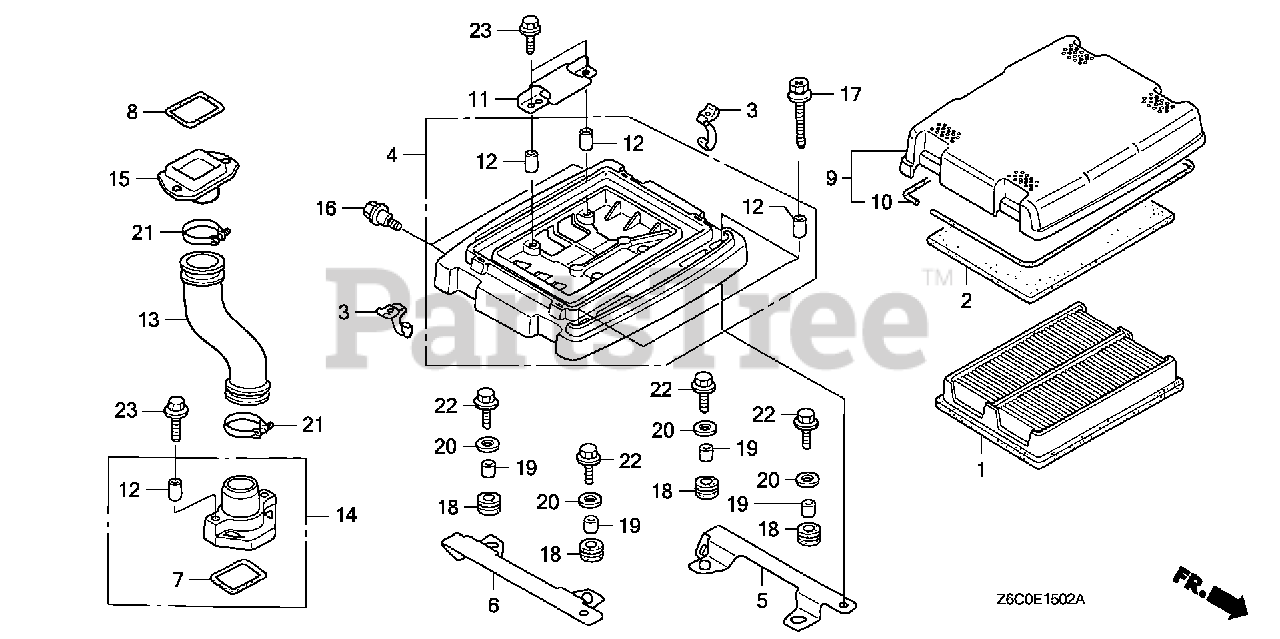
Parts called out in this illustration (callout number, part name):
1	ELEMENT, AIR CLEANER
2	FILTER (OUTER)
3	CLIP, AIR CLEANER
4	HOUSING, AIR CLEANER
5	STAY, R. AIR CLEANER HOUSING
6	STAY, L. AIR CLEANER HOUSING
7	SEAL, AIR CLEANER HOUSING
8	SEAL, AIR CLEANER HOUSING
9	COVER ASSY., AIR CLEANER
10	SEAL, AIR CLEANER COVER
11	PLATE, AIR CLEANER SETTING
12	COLLAR A, AIR CLEANER
13	TUBE, AIR CLEANER CONNECTING
14	JOINT ASSY., CONNECTING TUBE (B)
15	JOINT A, CONNECTING TUBE
16	BOLT, FLANGE (6MM)
17	BOLT-WASHER (5X30)
18	RUBBER, CONTROL BOX
19	COLLAR, CONTROL BOX
20	WASHER, PLAIN (6MM)
21	BAND, AIR CLEANER CONNECTING TUBE (58)
22	BOLT, FLANGE (6X20)
23	BOLT, FLANGE (6X28)
